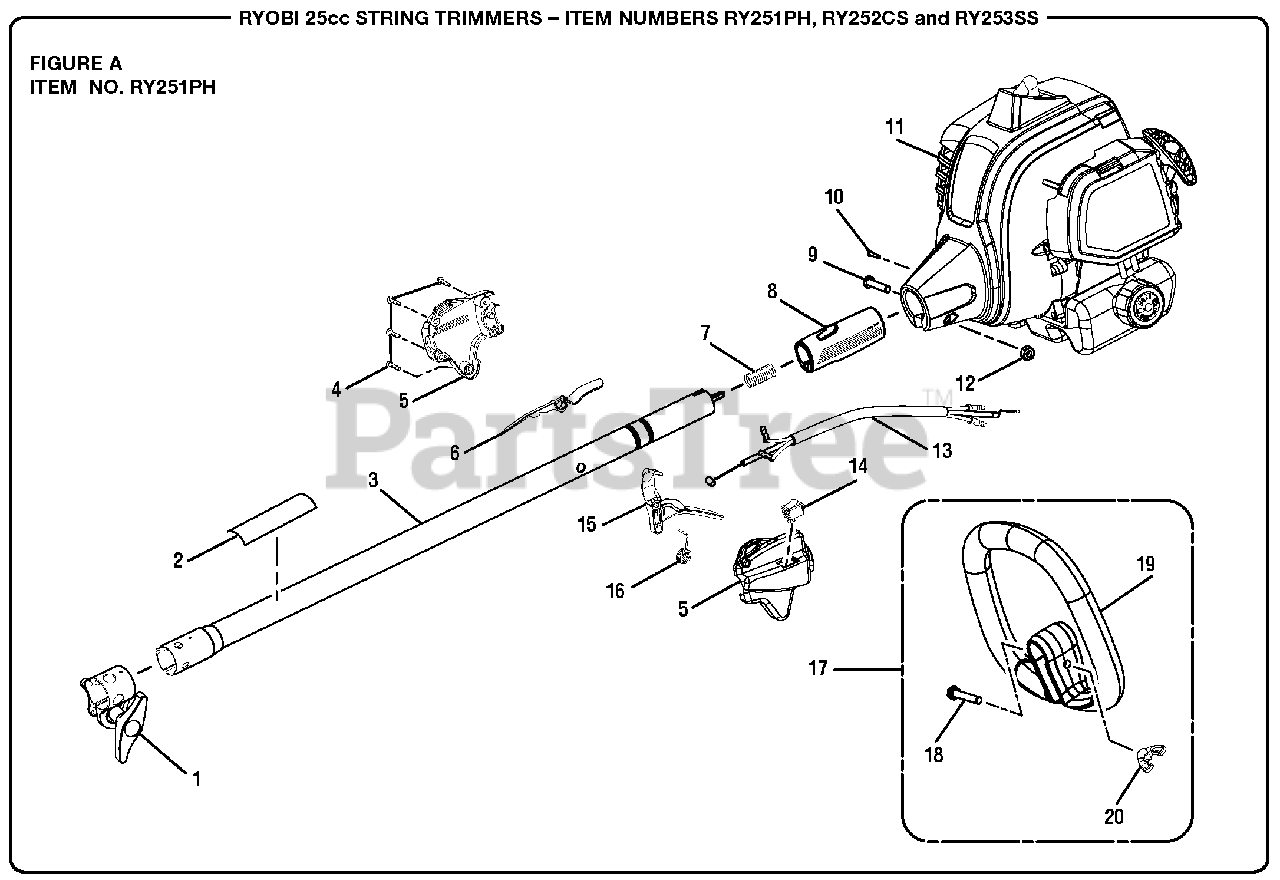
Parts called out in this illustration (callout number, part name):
1	Boom Clamp Assembly
2	Warning Icon Label
3	Upper Boom Assembly
4	Screw (M4 x 20 mm, T20 Torx Hd. S.T.)
5	Control Handle Assembly
6	Trigger Lock
7	Compression Spring
8	Rear Handle Grip
9	Screw (M6 x 30 mm, T27 Torx Button Hd.)
10	Screw (M4 x 8 mm, T20 Torx Pan Hd. S.T.)
11	Powerhead Assembly w/Labels
12	Hex Nut (M6 x 1)
13	Throttle Cable and Wire Assembly
14	On/Stop Switch
15	Trigger
16	Trigger Spring
17	Front Handle Assembly
18	Screw (1/4-20 x 40 mm, Cap Hex Hd.)
19	Front Handle
20	Wing Nut (1/4-20)
